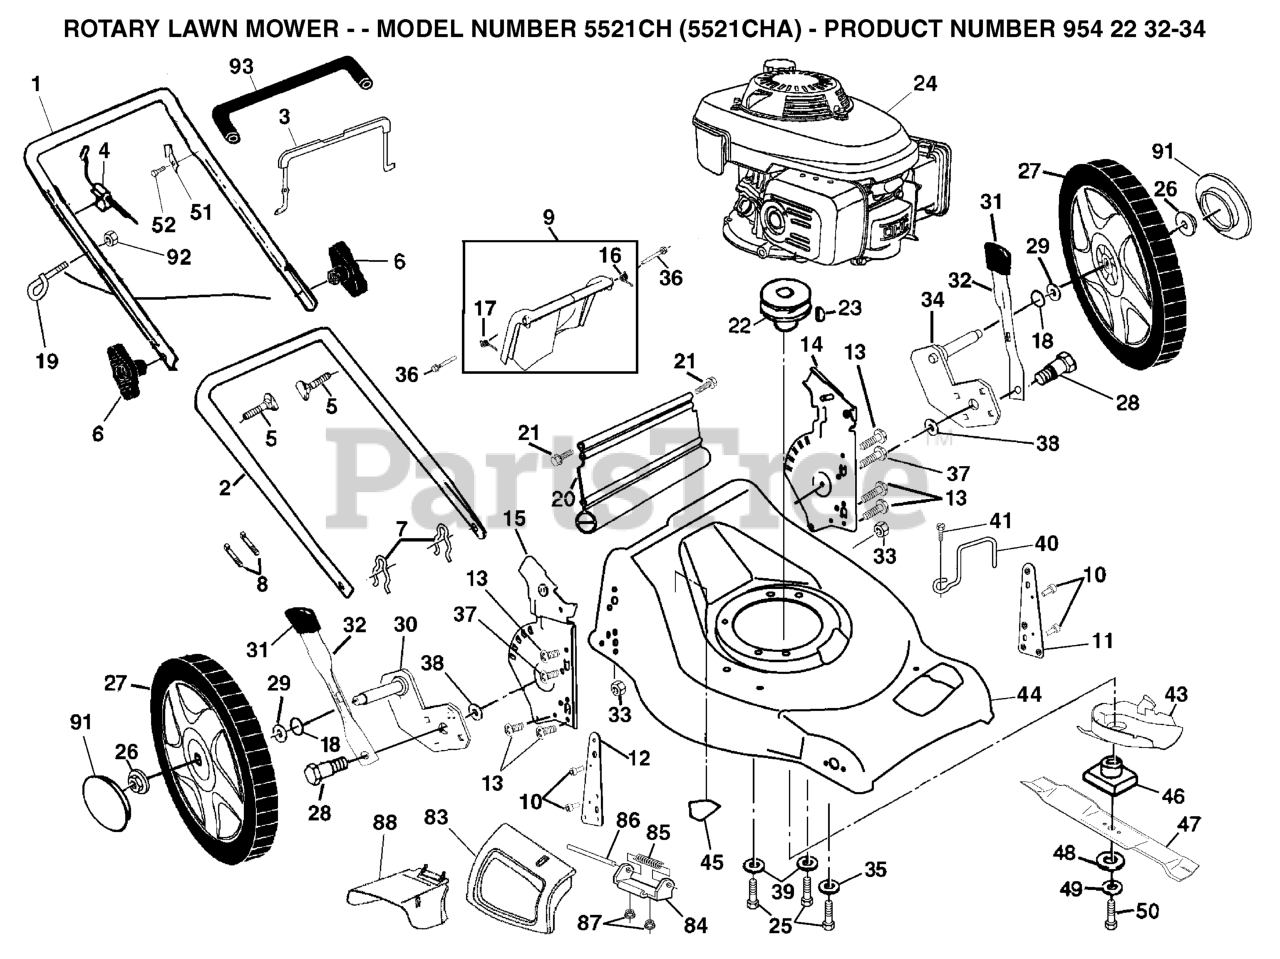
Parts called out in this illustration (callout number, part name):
1	UPPER HANDLE W/ GRIP
2	LOWER HANDLE
3	BAIL.CONT.MZR.FLAT.21
4	ENGINE ZONE CONTROL CABLE
5	HANDLE BOLT
6	HANDLE.KNOB.BLACK
7	HAIRPIN COTTER
8	TIE GUIDE
9	KIT.DOOR.RR.ASM.21.FWGD
10	RIVET BLIND
11	SUPPORT BRACKET LH
12	SUPPORT BRACKET RH
13	SCREW 14-20 X 5/8
14	HANDLE BRACKET ASSEMBLY, LEFT
15	HANDLE BRACKET ASSY. (RIGHT)
17	SPRING.REAR.DOOR.EZ.21
18	O-RING
19	ROPE, GUIDE
20	REAR SKIRT
21	HINGE SCREW
22	ENGINE PULLEY
23	HI PRO KEY PM WSL
25	BOLT 3/8-16X1-1/8
26	HEX FLANGE LOCKNT
27	RP WHEEL 14X2
28	SHOULDER BOLT
29	WASHER.FLAT.1/2
30	AXLE ARM ASSEMBLY RR
31	SELECTOR KNOB
32	SELECTOR SPRING
33	LOCKNUT
34	AXLE ARM ASSEMBLY LR
35	WASHER.ENGINE.BZP
37	SELF-TAPPING SCREW 5/16-18X3/4
38	SPACER.34X1.38X.22
39	WASHER,HARDEN
40	BOLT.HEX.HDWSH.5/16-18X1.00
41	KEEPER, BELT
43	BOTTOM BELT COVER
44	LAWN MOWER HOUSING
45	DECAL HYT
46	BLADE ADAPTOR
47	Blade, 21"
48	SADDLE WASHER
49	LOCKWASHER
50	SCREW, HEX HD 3/8-24 X 1-3/8
51	BRACKET UPSTOP
83	DOOR.MULCH.21.REAR.FWGD
84	BRACKET.ASM.HINGE.21.FWGD.
85	SPRING
86	ROD.HINGE.21
87	NUT
88	DEFLECTOR.CLIPPIN.21.FGD
91	HUBCAP
92	NUT
93	GRIP.HANDLE.FOAM
